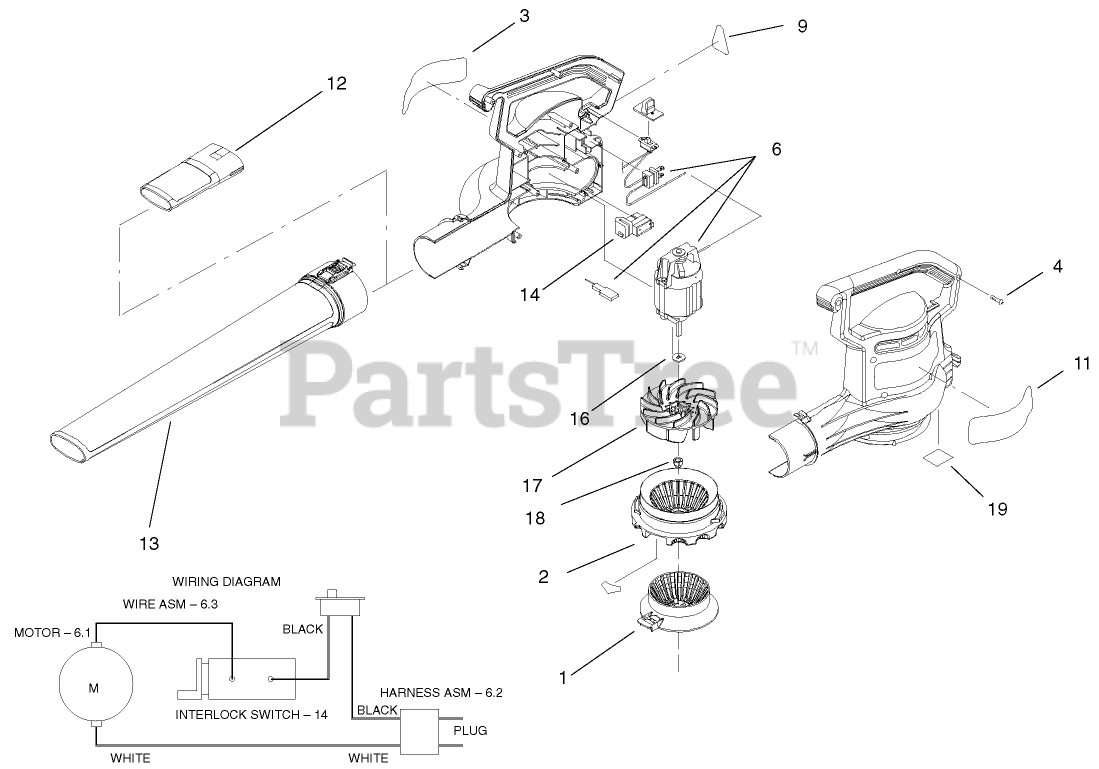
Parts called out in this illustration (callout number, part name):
1	CHOKE - AIR, RED
2	ASM-INLET COVER & DECAL
3	DECAL - WARNING
4	SCREW-PPH
6	ASM-Motor & Harness
9	DECAL - INFORMATION
11	DECAL, LOGO, SUPRBLWR
12	INSERT - TUBE
13	TUBE-BLOWER LONG
14	SWITCH - INTERLOCK
16	WASHER
17	IMPELLER - BLOWER
18	NUT-HEX
